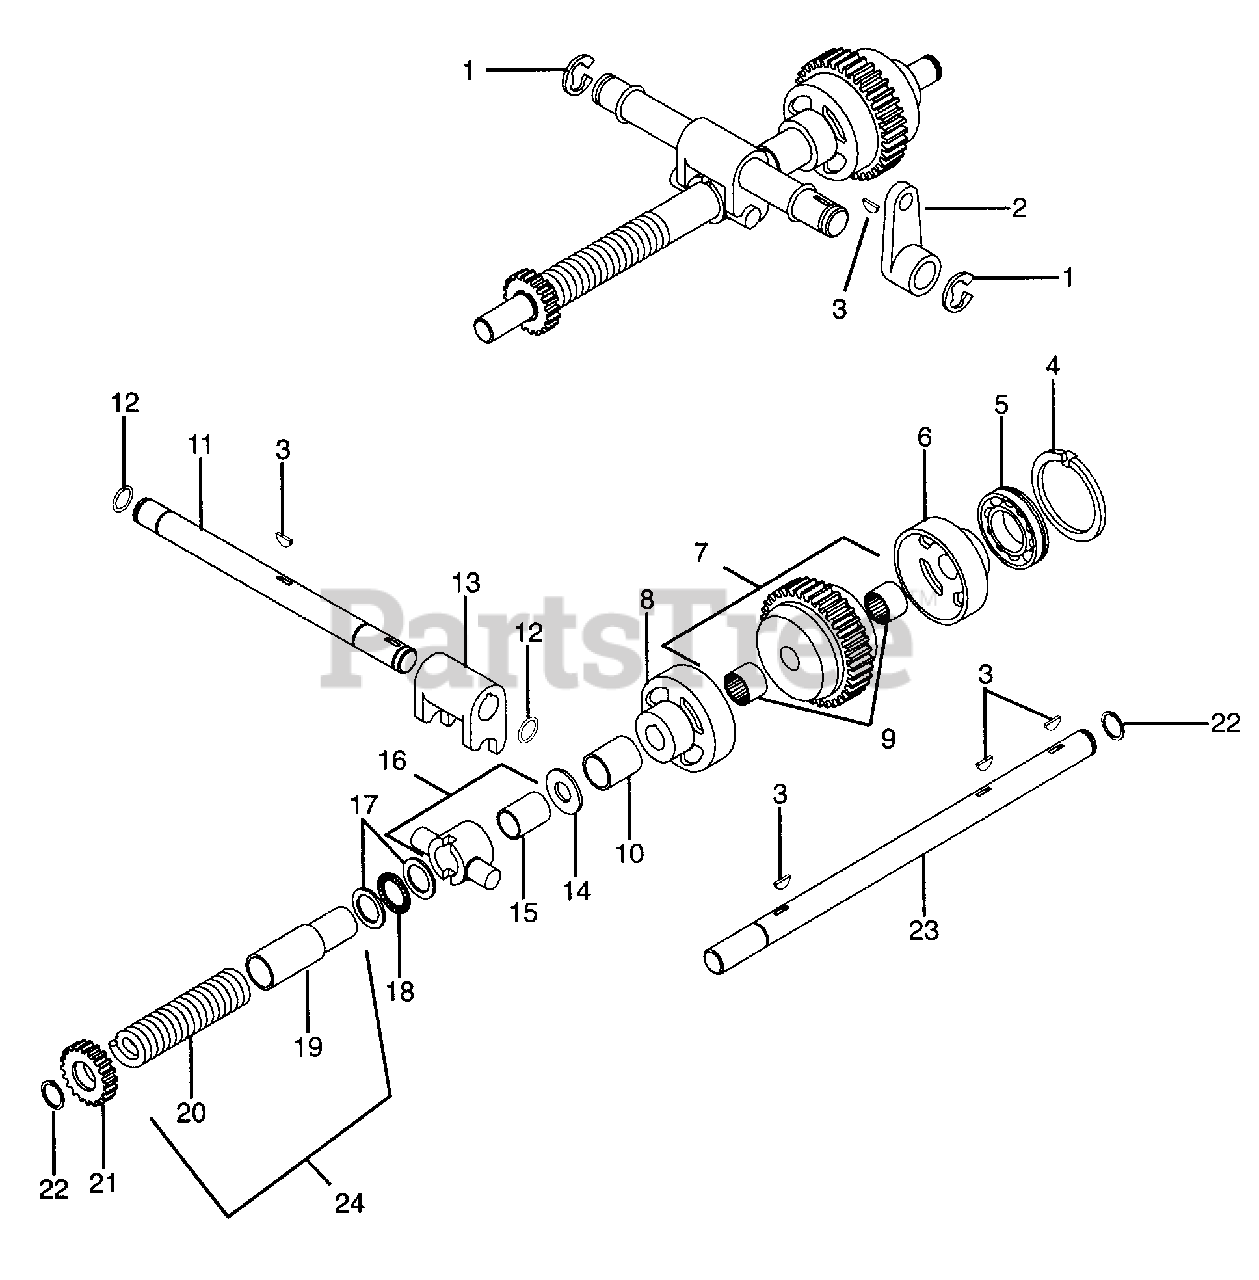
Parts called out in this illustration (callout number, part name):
1	Ring-Retaining-External .574 x .050
2	Lever-PTO
3	Key-Woodruff .19 x .75
4	Ring-Retaining-External 1.38 x 1.304
5	Bearing-Ball 1.38 x 2.44 x .55
6	Cup-Clutch
7	Assembly-Clutch Cone Bearing
8	Cup-Clutch
9	Bearing-Roller .75 x 1.0 x .50
10	Bushing-Sleeve .891 x 1.00 x 1.21
11	Shaft-PTO Yoke
12	O-Ring .625 x .75 x .062
13	Yoke-PTO
14	Bearing-N-Thrust .752 x 1.24 x .093
15	Bushing-Sleeve 1.000 x 1.120 x 1.000
16	Shifting Collar Assy
17	Washer-Thrust 1.55 x 1.002 x .093
18	Bearing-N-Thrust 1.0 x 1.55 x .078
19	Sleeve-PTO Throw Out
20	Spring-Compression .187 x 5.50
21	Gear-Spur PTO 10 DP 22 T
22	Ring-Retaining .697 x .93
23	Shaft-PTO Clutch
24	Kit-Sleeve and Spring
